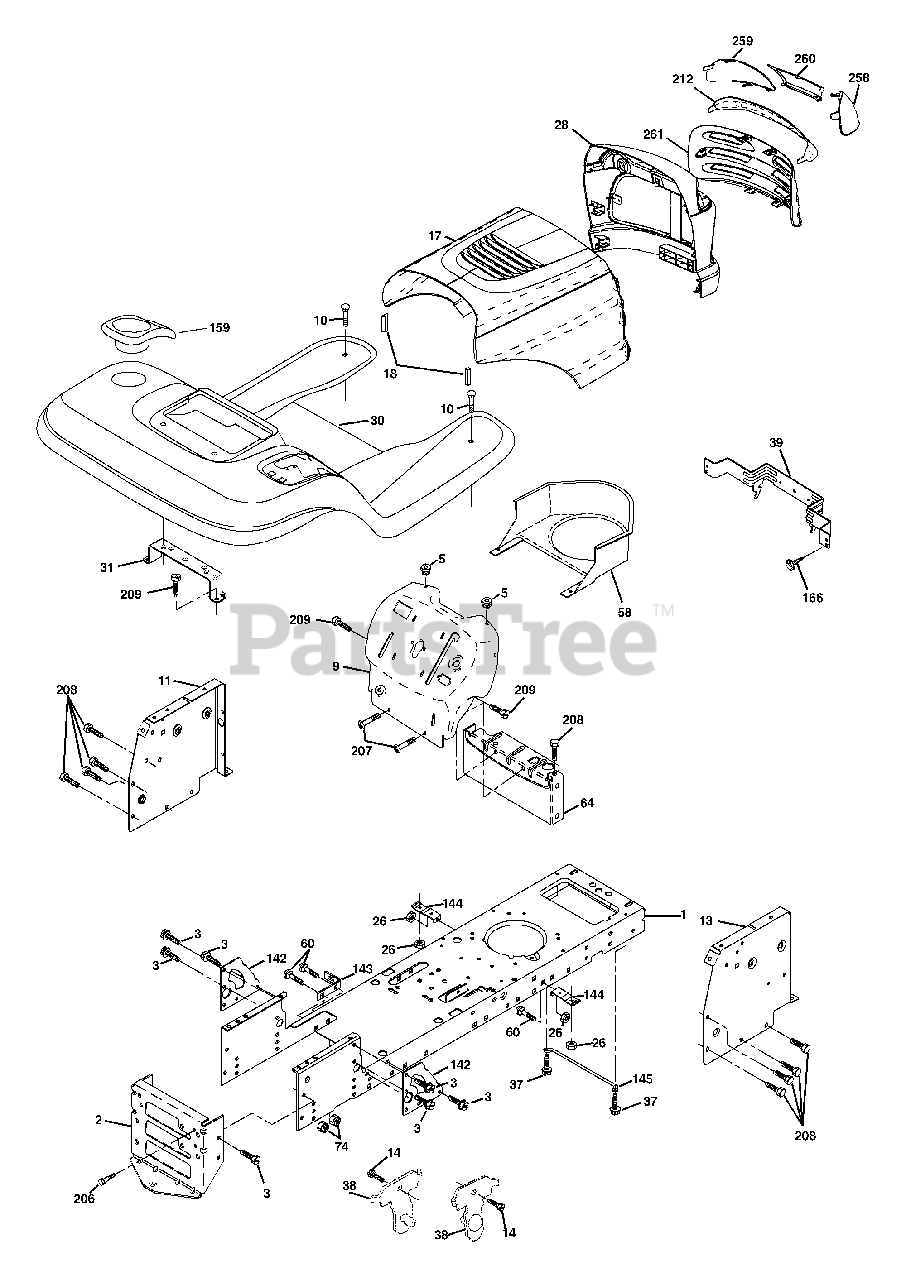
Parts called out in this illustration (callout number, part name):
1	Chassis Stamping
2	Drawbar, 12 Ga.
3	Screw 3/8-16 x 3/4
5	Bumper Hood/Dash
9	Dash Slkscr
10	Bolt Carriage 3/8-16 x 1
11	Panel Dash Lh
13	Panel Dash Rh
14	Screw Thdrol 3/8-16 x 1/2
17	Hood LT/PL
18	Bumper Hood
26	Nut Lock Hex W/Ins 3/8-16 Unc
28	Grille/Lens Asm
30	Fender Footrest
31	Bracket Fender
37	Screw Thdrol 6/16-18 x 1/2 TYT
38	Bracket Asm Pivot Mower Rear
39	Bracket Pivot
58	Air Duct Engine P/L
60	Bolt Rd Hd Sqnk 3/8-16 Unc x 3/4
64	Dash Lower STLT
74	Nut Crownlock 3/8-16 Unc
142	Plate Reinforcement STLT
143	Bracket Swaybar Chassis
144	Bracket Footrest
145	Rod Pivot Chassis/Hood
159	Cupholder
166	Screw Hw Hd Hi-Lo #13-16 x 3/4
206	Bolt Shoulder 5/16-18 TT
207	Screw Thdrol 5/16-18 x 1/2
208	Screw Thdrol 3/8-16x1/2 Ty-tt
209	Screw Hex Wsh Thdr. 3/8-16 x 3/4
212	Insert Lens Reflective
258	Lens Husq Laser LT Clear RH
259	Lens Husq Laser LT Clear LH
260	Cover Lens
261	Insert Grille
